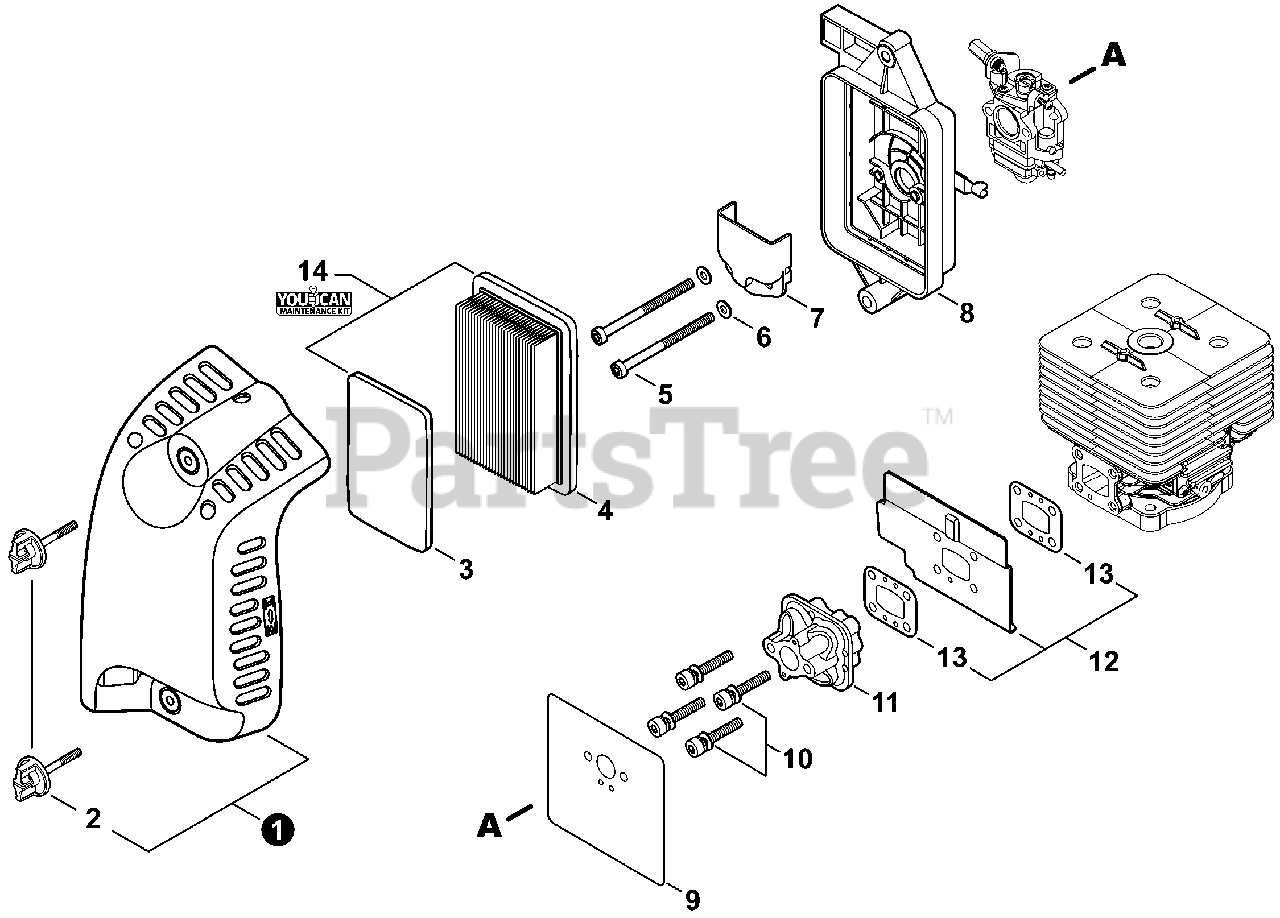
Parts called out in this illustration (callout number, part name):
1	COVER ASSY, AIR FILTER
2	THUMBSCREW
3	PRE-FILTER, FOAM
4	FILTER, AIR
5	BOLT SS M5×70
6	WASHER 5.3×10×1
7	PLATE, DEFLECTOR
8	CASE, AIR FILTER
9	GASKET, INTAKE
10	BOLT SS M5×30
11	INSULATOR, INTAKE
12	SHIELD ASSY, INTAKE HEAT
13	GASKET, INTAKE
14	TUNE-UP KIT - YOUCANT
